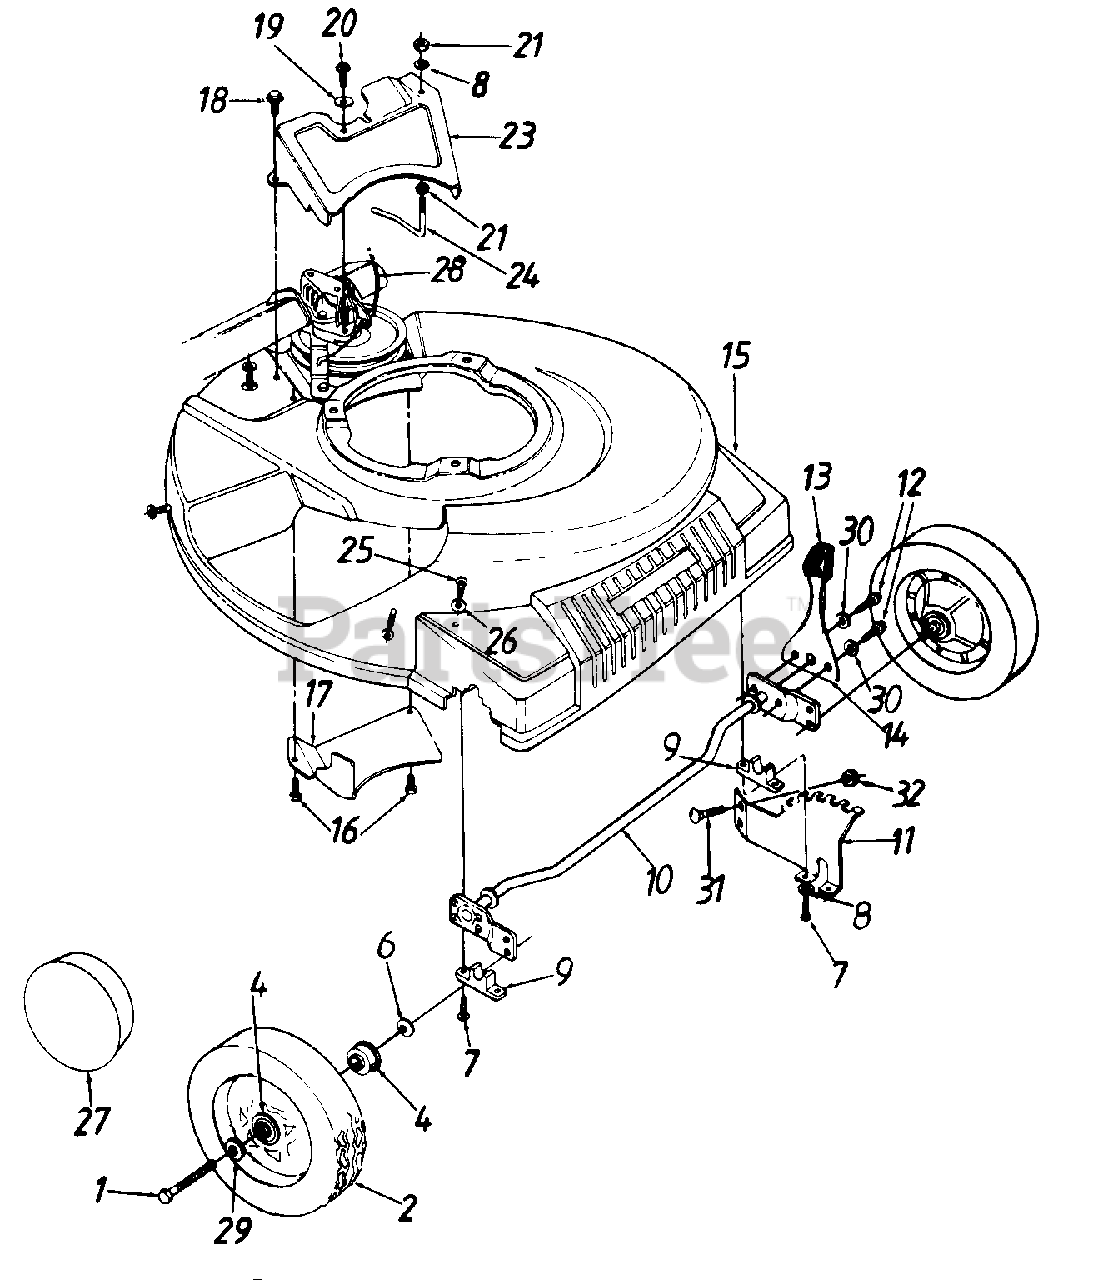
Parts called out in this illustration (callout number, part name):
1	Front Axle Bolt
2	Wheel Ass'y. Comp. (Beige)
4	Flange Ball Brg. .501" I.D.
6	Bell-Wash. .380" I.D. x .88
7	Hex Wash. Hd. Scr. 1/4-20 x 1" Lg.
8	L-Wash. 1/4" I.D.
9	Block Bushing
10	Axle Ass'y.
11	Height Adj. Bracket
12	Hex Wash. Hd. TT-Tap Scr. 1/4-20 x .38" Lg.
13	Knob
14	Spring Lever
15	Plastic Front End (Black)
16	Hex B-Tap Scr. 1/4" x .38"
19	Bell-Wash. .265" I.D. x .75"
20	Hex Wash. Hd. B-Tap Scr. 1/4 x .62" (Spec.)
21	Hex Nut 1/4-20 Thd.
25	Torx Truss Hd. Scr. 5/16 x .75"
26	Bell-Wash. .345" I.D. x .88" O.D.
27	Hub Cap (Beige)
28	S.P. Cable 50" Lg.
29	Wave Wash. .51" I.D. x .75"
30	External L-Wash. 1/4" I.D.
31	Carr. Bolt 1/4-20 x .5" Lg.
32	Hex L-Nut 1/4-20 Thd.
